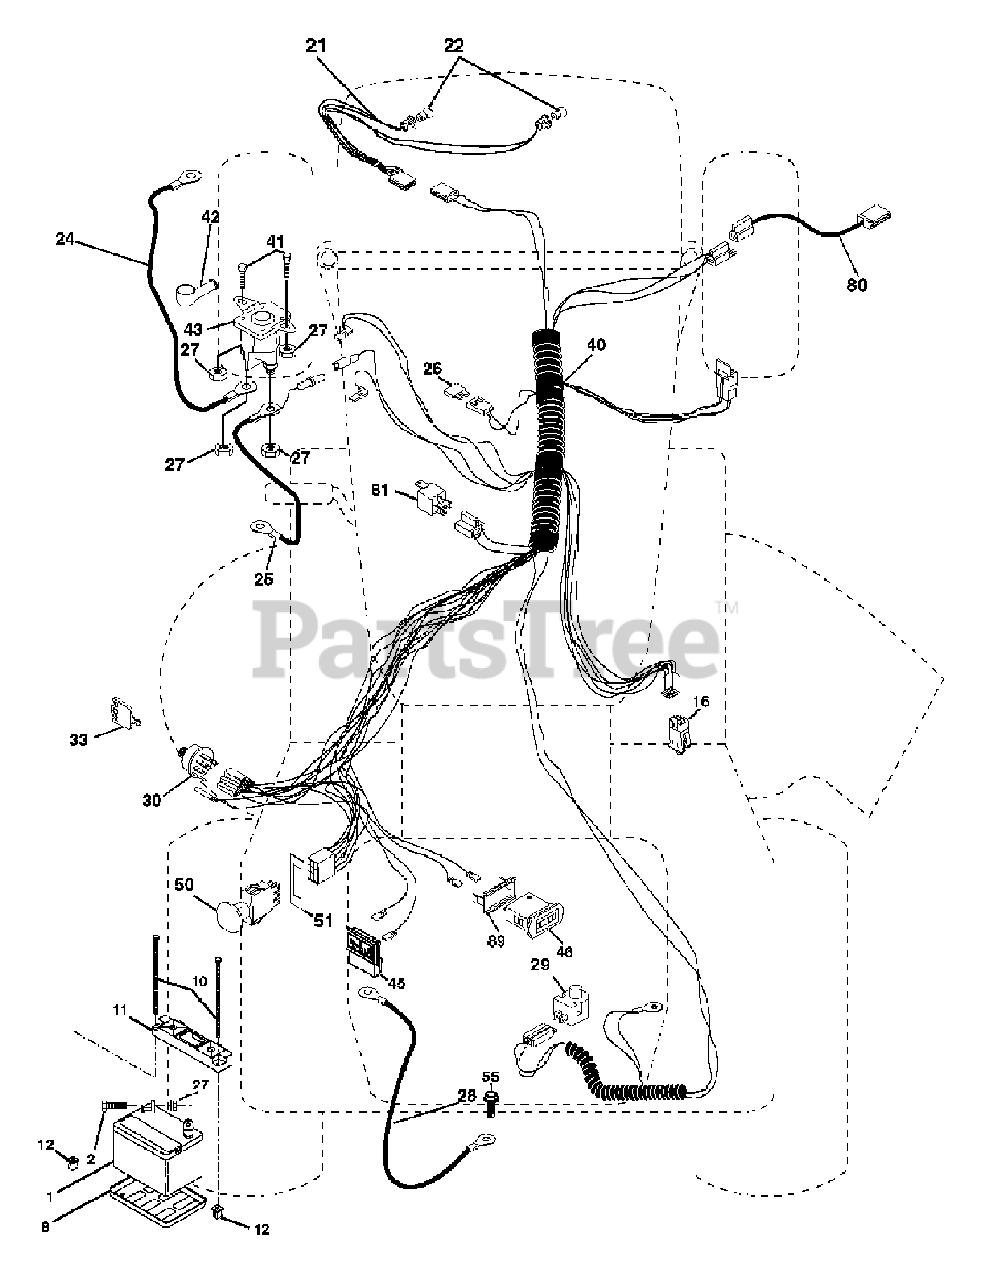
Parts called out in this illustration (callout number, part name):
1	Battery 12 Volt 35 AMP
2	Bolt Hex Hd 1/4-20unc X 3/4
8	Tray Battery
10	Bolt Brt Frt 1/4-20 x 75 Ainc
11	Holddown Battery Front Mount
12	Nut Push Nylon 1/4 Battery Frt
16	Switch Interlock Push-In
21	Harness Asm Light W/4152j
22	Bulb Light #1156
24	Cable Battery 6 Ga 22 red w/16 wire
25	Cable Battery 6 Ga 11 red
27	Nut Keps Hex 1/4-20 Unc
28	Cable Ground 6 Ga 21 black
29	Switch Plunger Nc Gray
30	Switch Ign
33	Key Ign Molded Generic
40	Harness Ign.
41	Bolt Blk Fin Hex 1/4 - 20 x 1/2
42	Cover Terminal Red
43	Solenoid
45	Ammeter Rectangular 15 Amp
46	Meter Hour
50	Switch PTO
51	Ring Retainer PTO
55	Screw Thdrol 5/16-18 x 1-1/2 Tyt
80	Harness Clutch Evx
81	Relay Asm.
89	Bracket Snap-In Hourmeter
